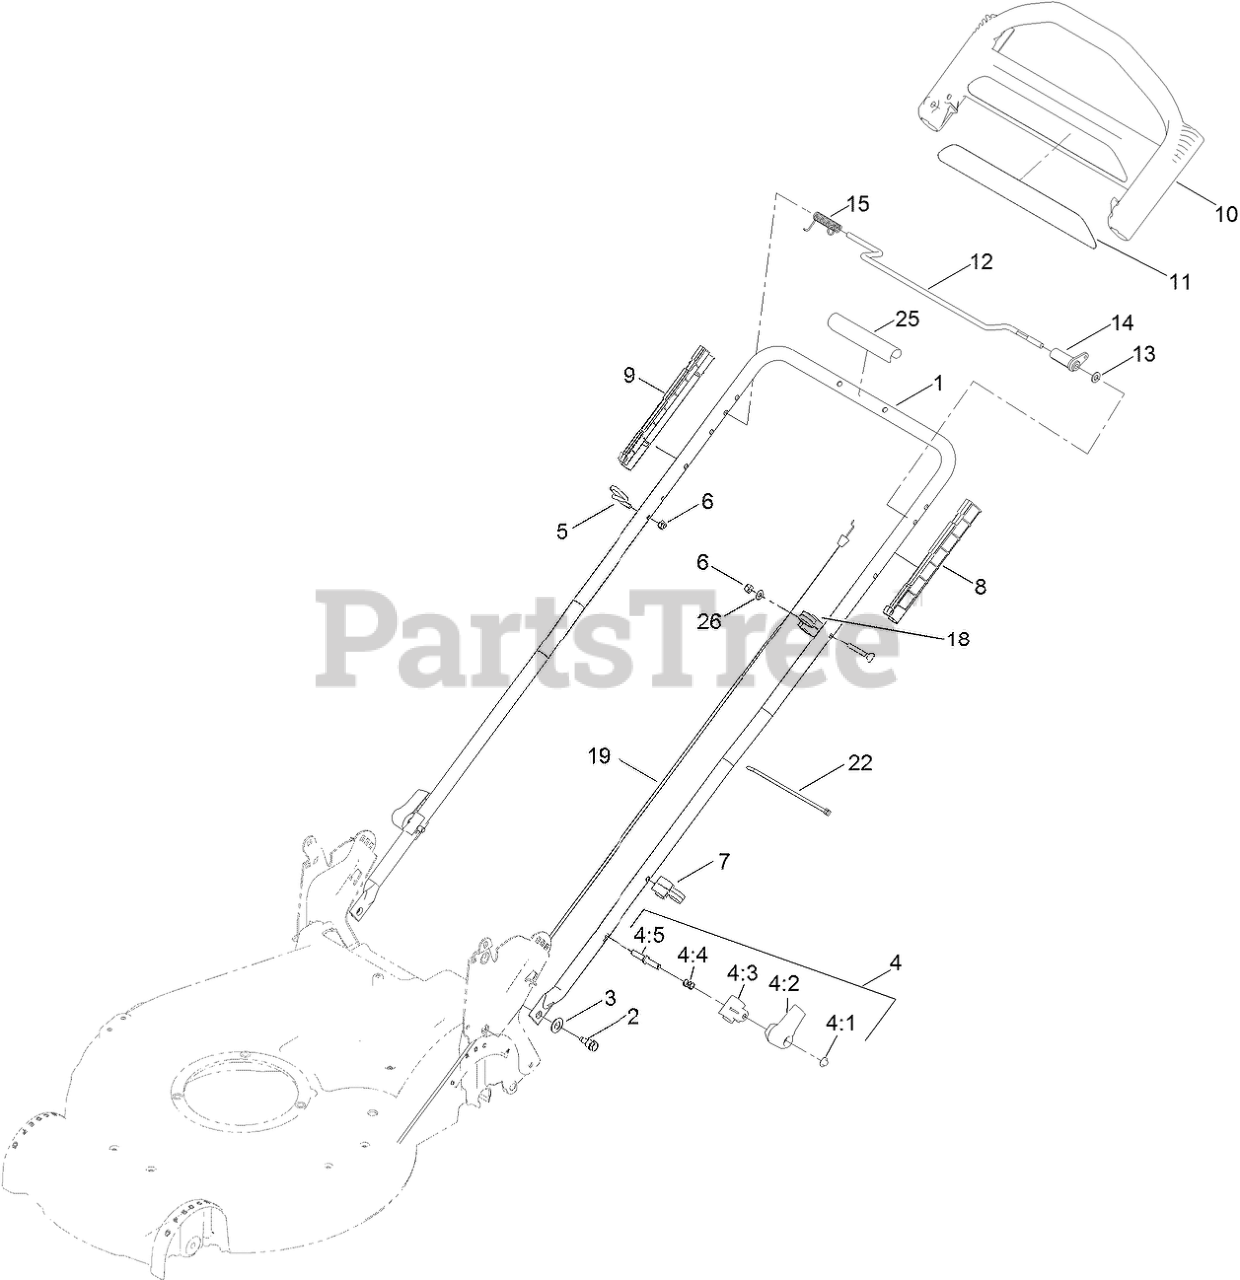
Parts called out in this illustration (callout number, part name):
2	BOLT-SHOULDER
3	WASHER-SPRING, CONICAL
4	QUICK RELEASE ASM
4:1	NUT-PUSH
4:2	LEVER
4:3	ANCHOR-SPRING
4:4	SPRING-COMPRESSION
4:5	ROD-RELEASE
5	GUIDE-ROPE
6	NUT-LOCK, NI
7	GUIDE-CABLE
8	GUIDE-LH
9	GUIDE-RH
10	HANDLE-CONTROL
12	BAR-CONTROL, TRACTION
13	WASHER-PLAIN
14	LEVER-TRACTION
18	ANCHOR-CABLE
19	CABLE-TRACTION
22	TIE-CABLE
25	HANDLE-COVER
26	WASHER-FLAT
